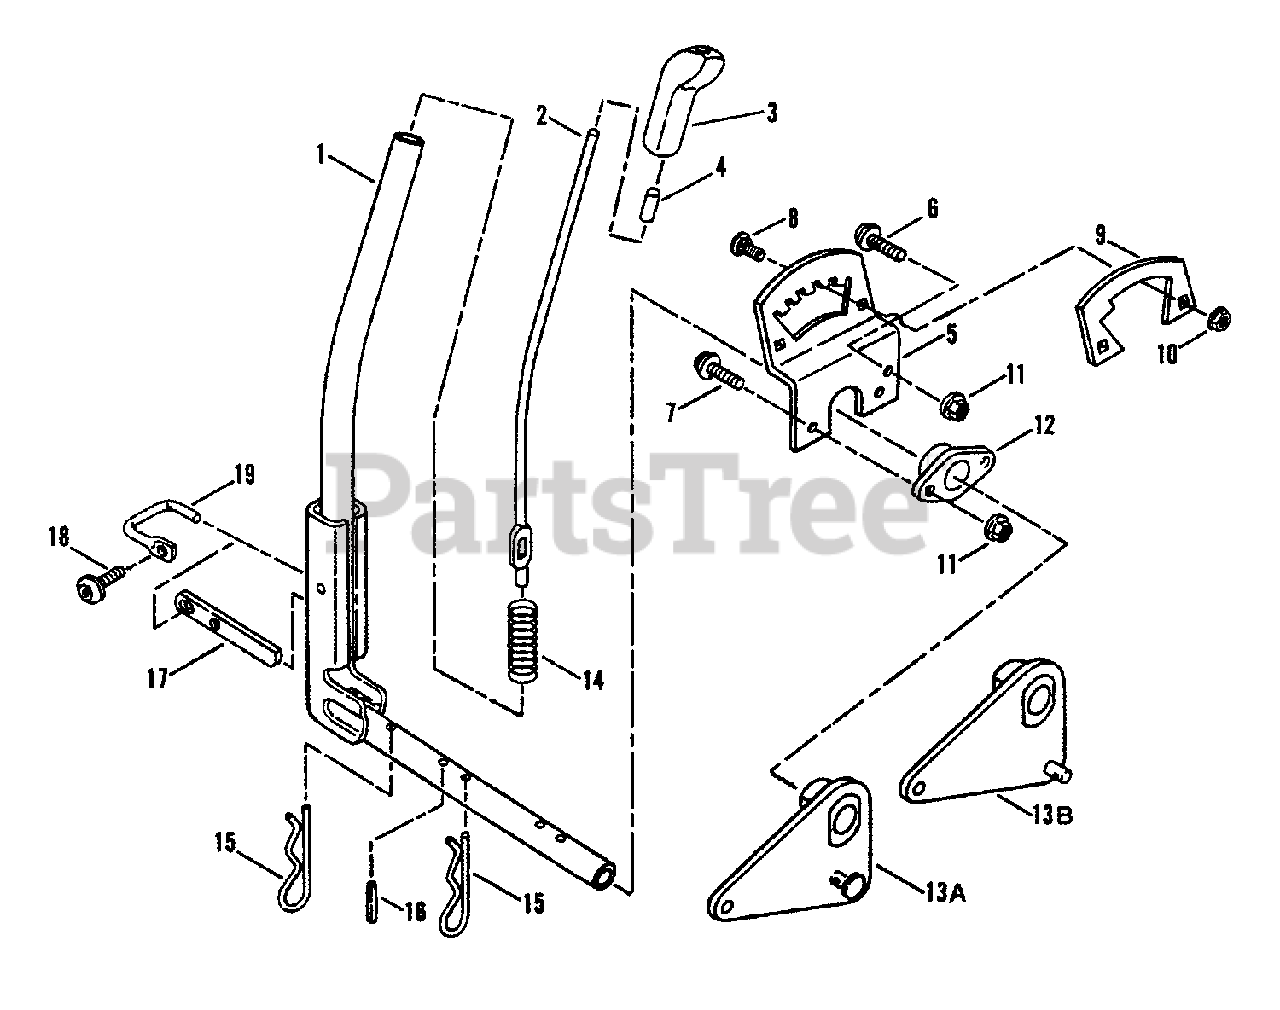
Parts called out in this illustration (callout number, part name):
1	WELDMENT, Implement Lift Lever-33/42
1	WELDMENT, Implement Lift Lever-30/38
2	ROD, Lift Lever
3	KNOB, Lift Handle
4	CAP, Lift Lever Rod
5	QUADRANT, Lift Lever
6	SCREW, 5/16-18 x 5/8" Truss Head (Torx)
7	SCREW, 5/16-18 x 7/8" Truss Head (Torx)
8	BOLT, 1/4-20 x 1/2" Short Neck Carriage, GR5
9	DETENT, High Cut Lockout
10	NUT, 1/4-20 Hex Flange Lock
11	NUT, 5/16-18 Hex Flange Lock, GR5
12	PIVOT, Lift Lever
13A	WELDMENT, Bellcrank, Lift Lever, 33
13B	WELDMENT, Bellcrank, Lift Lever, 30/38/42
14	SPRING, Latch Detent
15	COTTER HAIR PIN, 2-5/8"
16	PIN, Dowel, 1/4 x 1-1/8"
17	DETENT, Lift Lever
18	SCREW, 1/4-20 x 5/8" Pan Head Self-Tap (Torx)
19	PIVOT, Latch Detent
